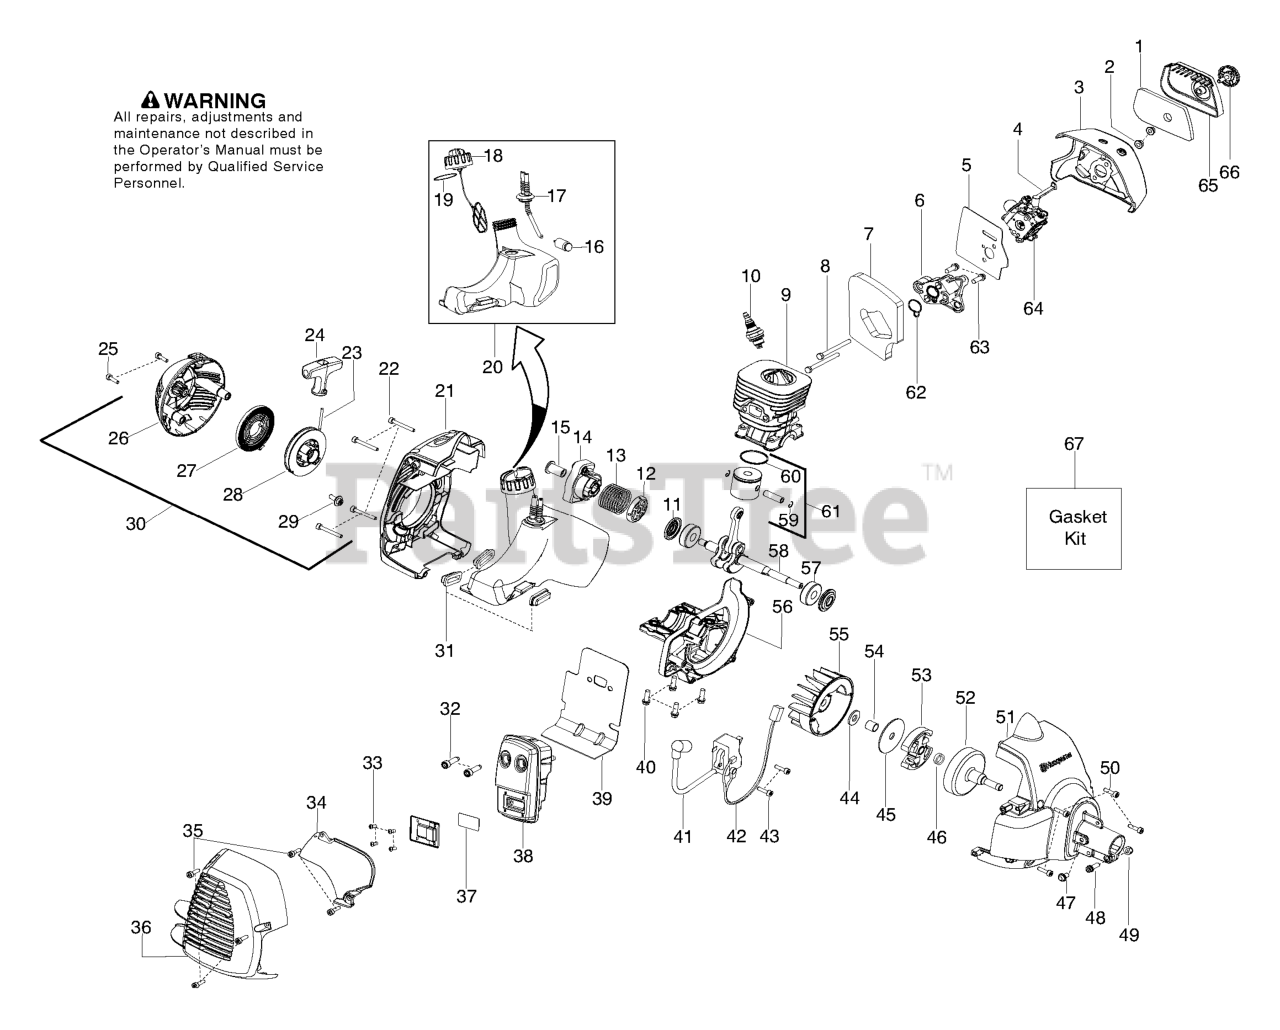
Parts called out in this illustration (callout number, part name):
1	FILTER AIRBOX
3	AIRBOX
4	KIT CHOKE LEVER 28CC
5	KIT GASKET CARB
6	CARB ADAPTOR
7	KIT GASKET 28CC TRIMMER
8	BOLT CARB ADAPTOR
9	CYLINDER
10	Plug-Spark (RCJ-6Y)
11	KIT SEAL CRANKSHAFT
12	WASHER STARTER
13	SPRING STARTER CUP
14	ASSY STARTER CUP
15	COUPLING STARTER
16	FUEL PICK-UP ASSY
17	KIT FUEL LINE
18	ASSY-CAP W/RETAINER
19	O RING NITRILE
20	ASSY FUEL TANK
21	REAR SHROUD
24	STARTER HANDLE GRAY
26	HSG STARTER W/EYELET
27	%KIT STARTER SPRING
28	KIT STARTER PULLEY
30	STARTER HSG ASSY
31	ISOLATOR FUEL TANK
32	BOLT MUFFLER
33	SCREW-10-16 X 1/2 HI-LO
34	SHIELD HEAT
35	SCREW M4 X 1.75 PT 16MM
36	MUFFLER GUARD
37	KIT SPARK ARRESTOR SCREEN
38	ASSY MUFFLER
39	GASKET PAPER METAL
40	SCREW-M5-0.8 X 25MM(TAP)
41	IGNITION MODULE MB45
42	ASSY MODULE LEAD WIRE
43	SCREW M4 X .70 TT 16MM
45	WASHER-CLUTCH
46	SPACER-CLUTCH
49	NUT HEX LOCK 10-24
50	SCREW M4 X .70 TT 16MM
51	FAN HSG ASSY
52	ASSY-CLUTCH DRUM
53	ASSEMBLY CLUTCH
54	SPACER FLYWHEEL
56	CRANKCASE 28CC MACHINED
57	BEARING RADIAL BALL (6201)
58	KIT CRANKSHAFT ASSY
59	WRIST PIN RET.
60	RING PISTON
61	KIT PISTON 28CC TRIMMER
62	KIT GASKET 28CC TRIMMER
63	SCREW-M5-0.8 X 25MM(TAP)
64	KIT CARBURETOR
65	COVER-AIR BOX
66	KNOB ASSY AIRBOX COVER
67	KIT GASKET 28CC TRIMMER
